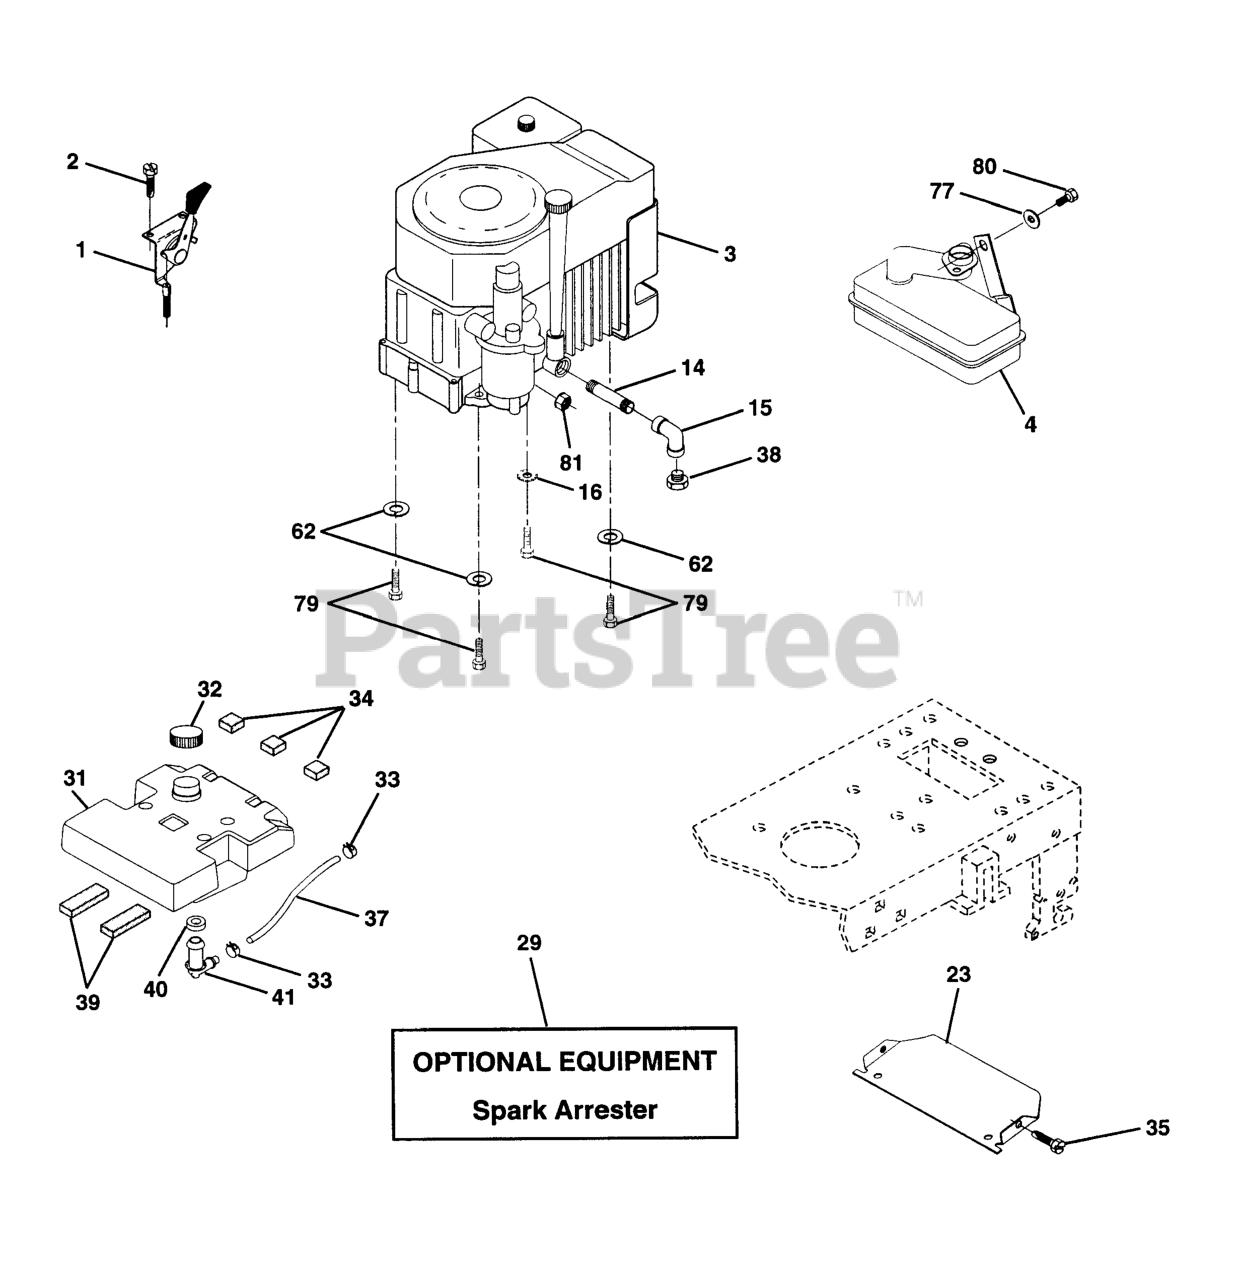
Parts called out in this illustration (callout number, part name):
1	CONTROL SWITCH 27 LH
2	SCREW LT
4	MUFFLER LT 12.5
14	Nipple Pipe 3/8 Npt X 3-1/2
15	ELBOW
16	WASHER EXT TOOTH LOCK 5/16
23	SHIELD HEAT
29	KIT.SPARK ARRESTOR 794945 B&S
31	TANK.FUEL(3.5.GAL)
32	FUEL CAP
33	HOSE CLAMP
34	PAD-SPACER LT
35	SCREW.THDROL.5/16-18X3/4.TTY
37	HOSE T
38	Plug Oil Drain
39	PAD IDLER TI
40	BUSHING OUTLET T
41	STEM FUEL TANK
62	WASHER.LOCK.HVY.HLCL.SPR.5/16
77	WASHER
79	BOLT, HEX
80	Bolt Hex Hd. 5/16-18unc x 1/2
81	NUT FLANGE 1/4-20 STARTER NUT
